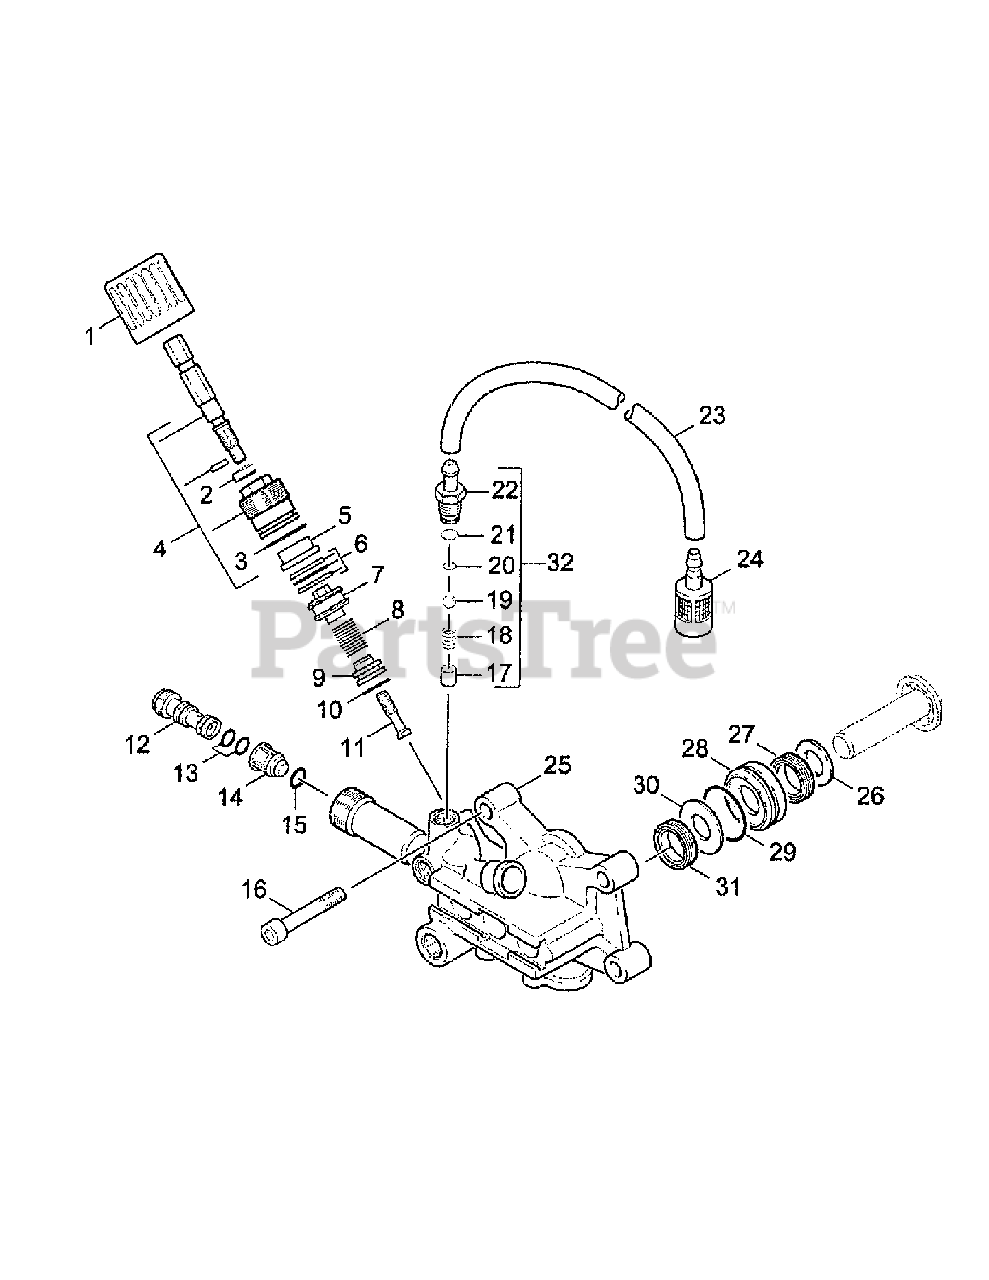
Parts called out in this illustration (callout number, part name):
1	Handle
2	Gasket
3	Gasket
4	Union Scre
5	Sleeve
6	Gasket
7	Piston
8	Helical Spring
9	Valve Seat
10	Gasket
11	Screw
12	Nozzle Insert
13	Gasket
14	Valve Pin
15	Gasket
16	Screw
17	Sleeve
18	Helical Spring
19	Ball
21	Gasket
22	Nipple
23	Hose
24	Filter
25	Cylinder Head
26	Washer
27	Grooved Ring
28	Bushing
29	Gasket
30	Washer
31	Grooved Ring
32	Check Valve
